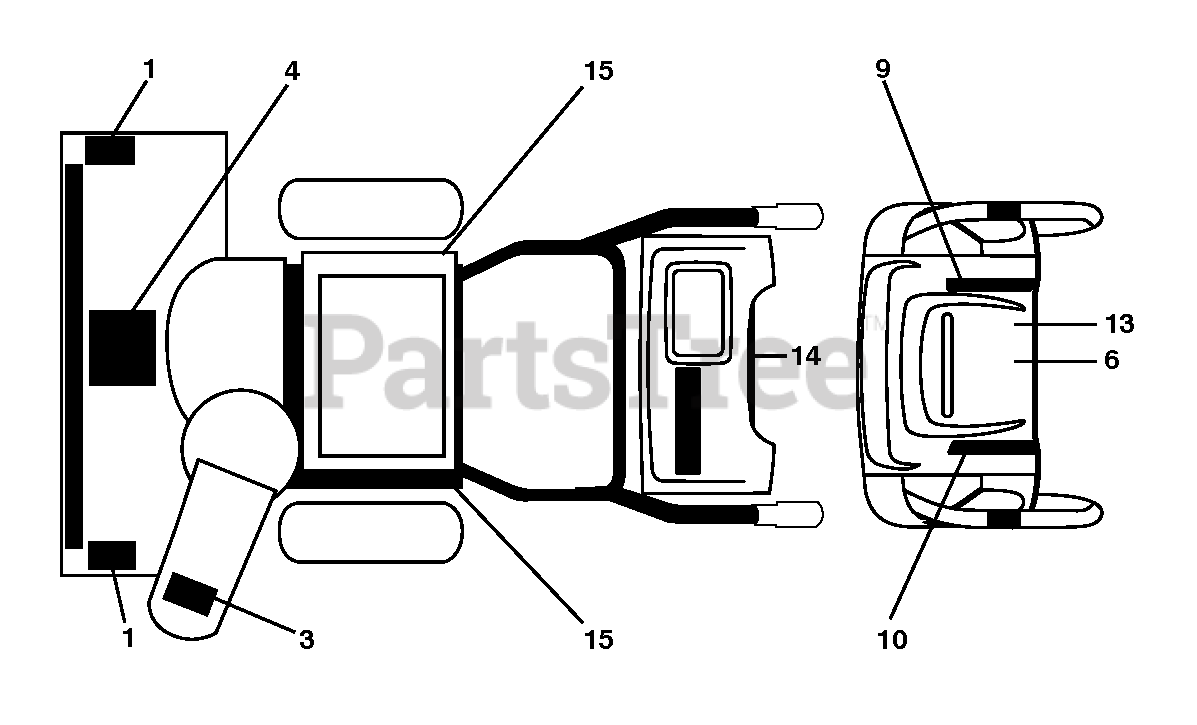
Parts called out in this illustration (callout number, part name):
1	DECAL.AUGER.SAFETY.
3	DECAL.CHUTE.SAFETY.
4	DECAL.AUGER."
9	DECAL CONSOLE DECAL DECAL.SNOW
10	DECAL CONSOLE DECAL DECAL.SNOW
13	DECAL.CONSOLE.HAND.WARMER
14	DECAL.NOISE.LEVEL.105DB/CE.EAC
15	DECAL.BELT.GUARD.
